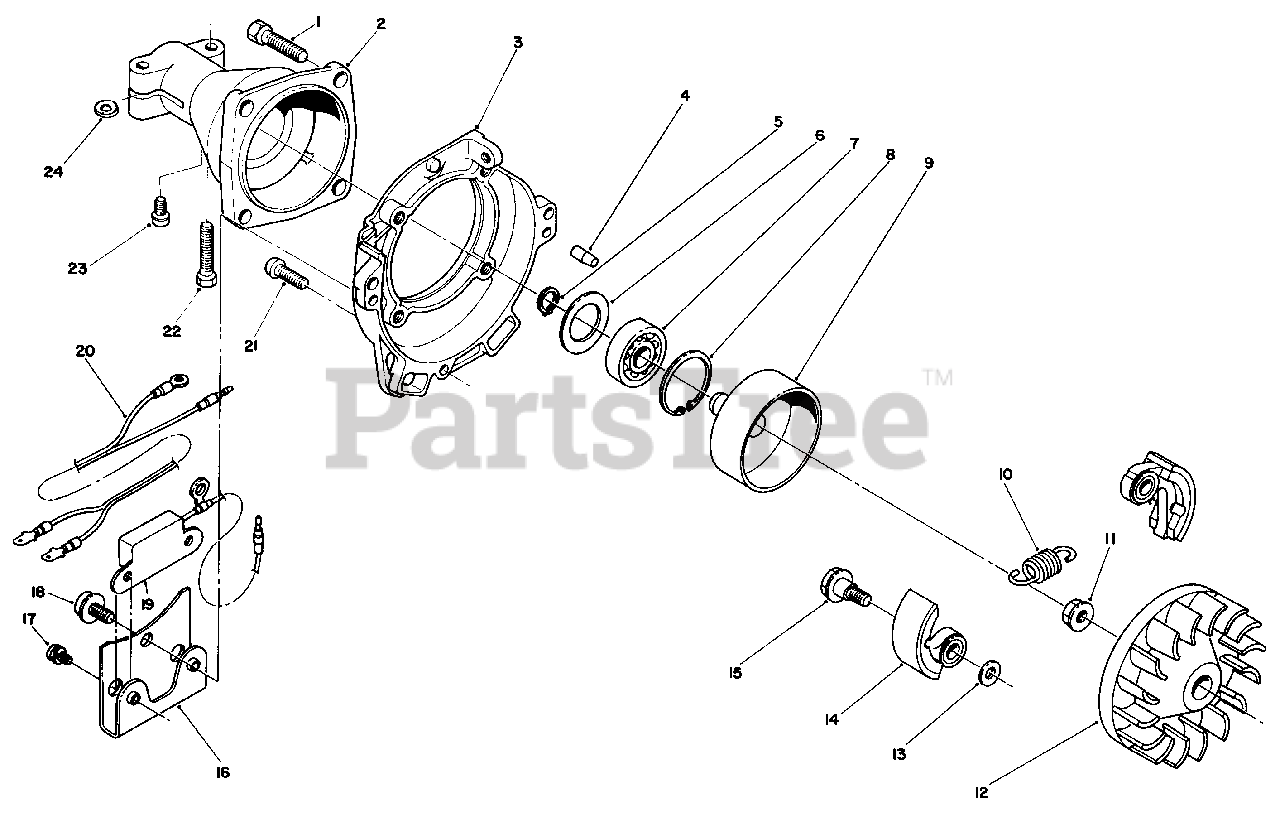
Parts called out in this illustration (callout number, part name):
1	Screw & Washer
2	Case, Clutch
3	Case, Fan
4	Pin, Dowel
5	Snap Ring
7	Bearing, Ball
8	Snap Ring
9	Drum, Clutch
10	Spring
11	Nut, Conical Spring
14	Shoe, Clutch
15	Bolt, Clutch
16	Bracket, Unit
17	Screw & Washer
18	Screw & Washer
19	Unit, Transistor
20	Wire, Lead
21	Bolt & Washer
22	Bolt & Washer
23	Screw & Washer
24	Washer, Spacer
